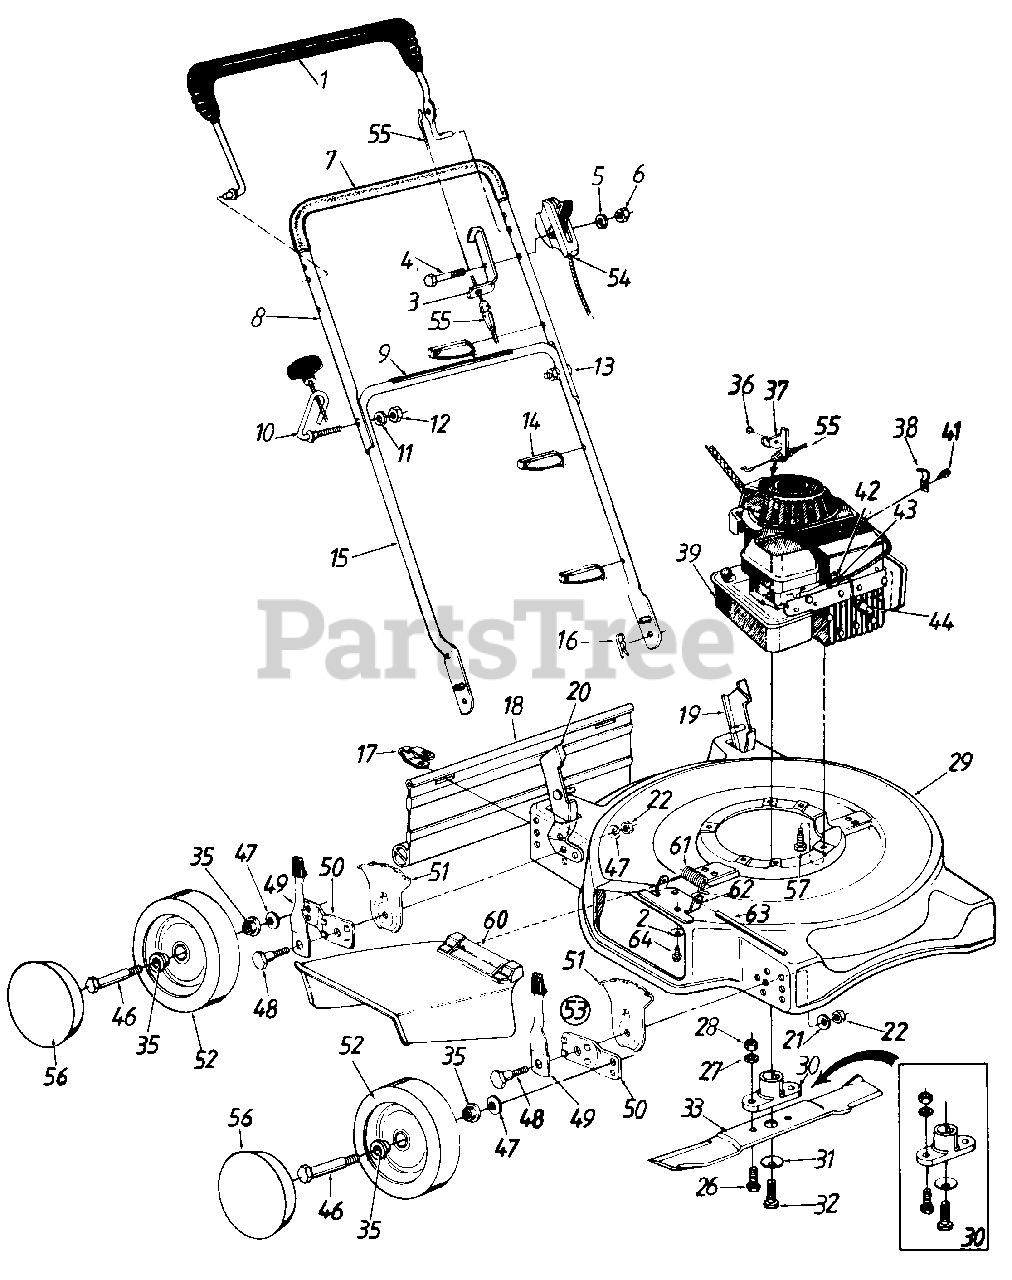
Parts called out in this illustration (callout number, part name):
1	Control Handle Ass'y. w/Plastic
2	Bell-Wash. 1/4" I.D.
3	Cable Brkt.
4	Hex Bolt 1/4-28 x 1.75" Lg.
5	Spr. Wash. 1/4" I.D.
6	Hex Nut 1/4-28 Thd.
7	Foam Grip
8	Upper Handle
9	Instruction Label-Handle
10	Rope Guide Bolt
11	L-Wash. 5/16" I.D.*
12	Hex Nut 5/16-18 Thd.
13	Curved Carriage Bolt 5/16-18 x 1.38" Lg.
14	Cable Tie
15	Lower Handle
16	Hairpin Cotter
17	Hinge Clip
18	Rear Flap
19	Handle Bracket Ass'y.-L.H.
20	Handle Bracket Ass'y.-R.H.
21	Bell-Wash. .39" I.D. x 1.38"
22	Hex Nut 3/8-16 Thd.*
26	Hex Bolt 3/8-24 x 1" Lg.
27	L-Wash. 318" I.D.*
28	Hex Nut 3/8-24 Thd.*
31	Bell-Wash. .39" I.D.
32	Hex Bolt 3/8-24 x 1.5" Lg.
33	Hex Bolt 3/8-24 x 1.5" Lg.
35	Ball Bearing
37	Cable Bracket
38	Cable Clamp
39	Engine
41	Hex B-Tap Scr. #10 x .38"
43	Hex AB-Tap Scr. #8 x .38"
44	Spark Plug Boot
47	Bell-Wash. .400" I.D. x .88"
48	Shld. Bolt .50" Dia. x .357"
49	Spring Lever Ass'y. w/Knob
51	Height Adj. Plate
52	Wheel Ass'y. Comp.
53	Height Adj. Ass'y. Comp.-R.F. & L.R.
54	Throttle Control Ass'y. Comp.-51.62
55	Control Cable-36"
56	Hub Caps
57	Hex L-Wash. Hd. Scr. 3/8-16 x 1.0" Lg.
60	Chute Deflector Ass'y.
61	Torsion Spring
62	Adapter Plate
63	Hinge Pin
64	Hex Self-Tap Scr. 1/4-20 x .5" Lg.
